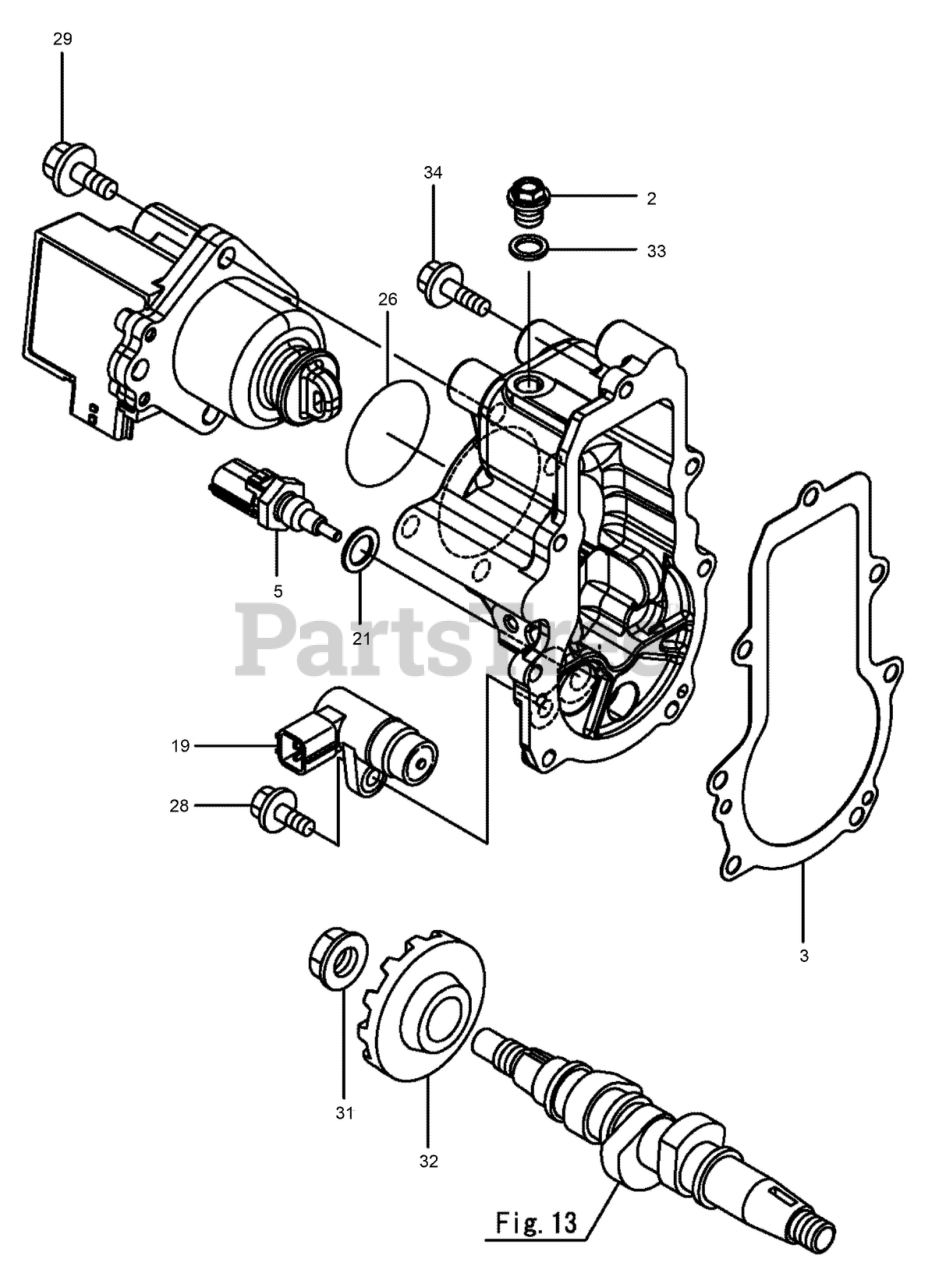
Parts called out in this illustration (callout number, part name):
3	GASKET
5	SENSOR-OIL TEMP
19	SENSOR
21	WASHER-SEAL
26	O-RING
33	WASHER-SEAL
